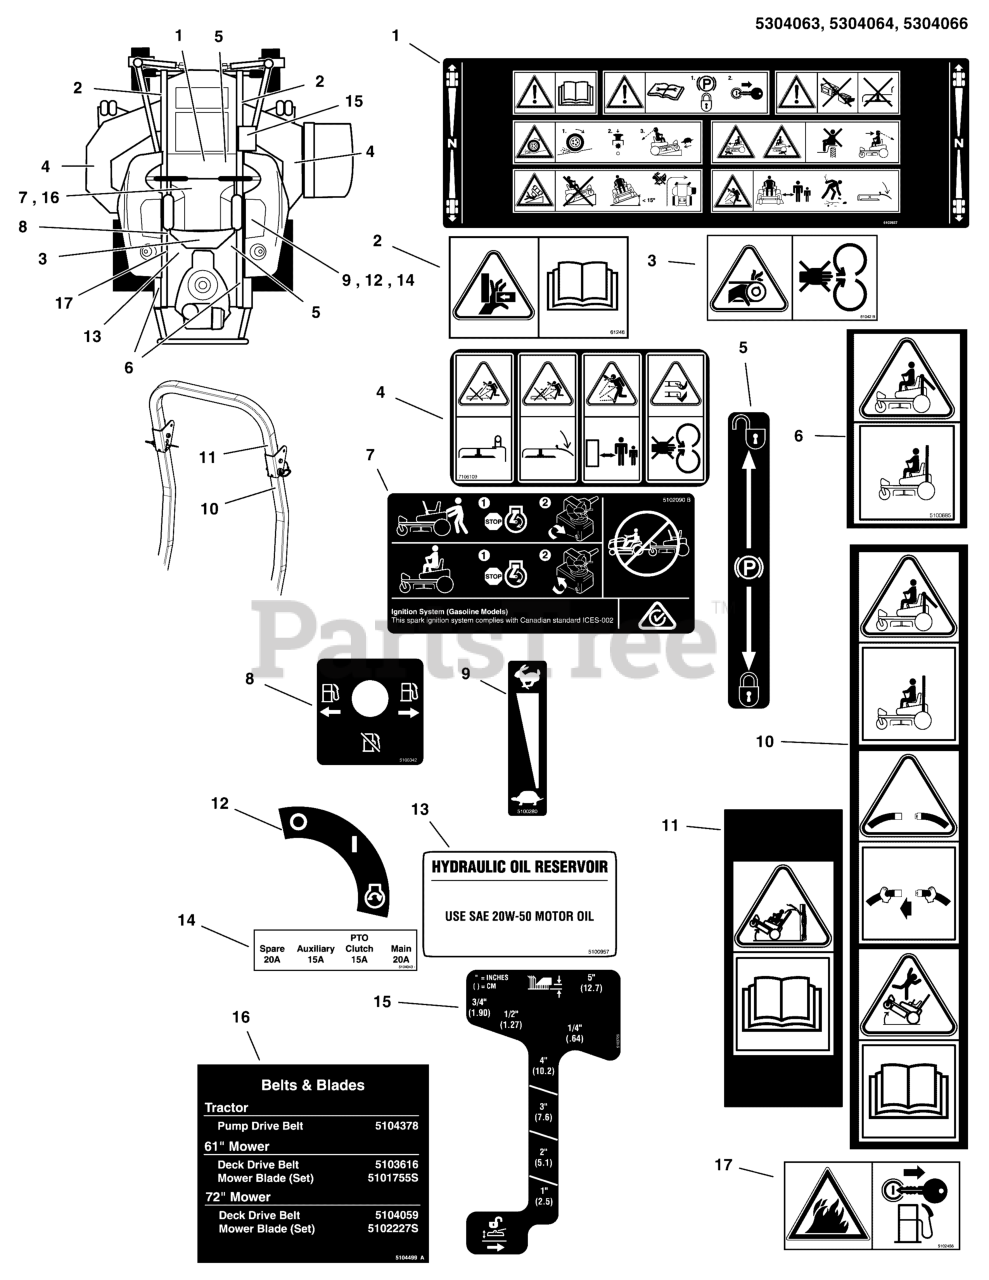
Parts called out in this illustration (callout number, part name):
1	DECAL, MAIN SAFETY, ANSI CE
2	DECAL, PINCH POINT, CE
3	DECAL, CE DANGER
4	DECAL, DISCHARGE SAFETY, EXPORT
5	DECAL, PARKING BRAKE SYMBOLS
6	DECAL, WARNING, ROLL BAR, CE
7	DECAL, TRANSAXLE RELEASE, S200XT
8	DECAL, FUEL VALVE
9	DECAL, THROTTLE CONTROL
10	DECAL, SAFETY, CE ROPS (SV)
11	DECAL, SAFETY, CE ROPS, OBS (SV)
12	DECAL, IGNITION SWITCH
13	DECAL, HYDRAULIC OIL, SAE 20W50
14	DECAL, FUSE LOCATION, IS2100
15	DECAL, CUT HEIGHT, IS700/ZTS700
16	DECAL, BELT AND BLADE, IS3200Z
17	DECAL, FIRE ANSI EXPORT
